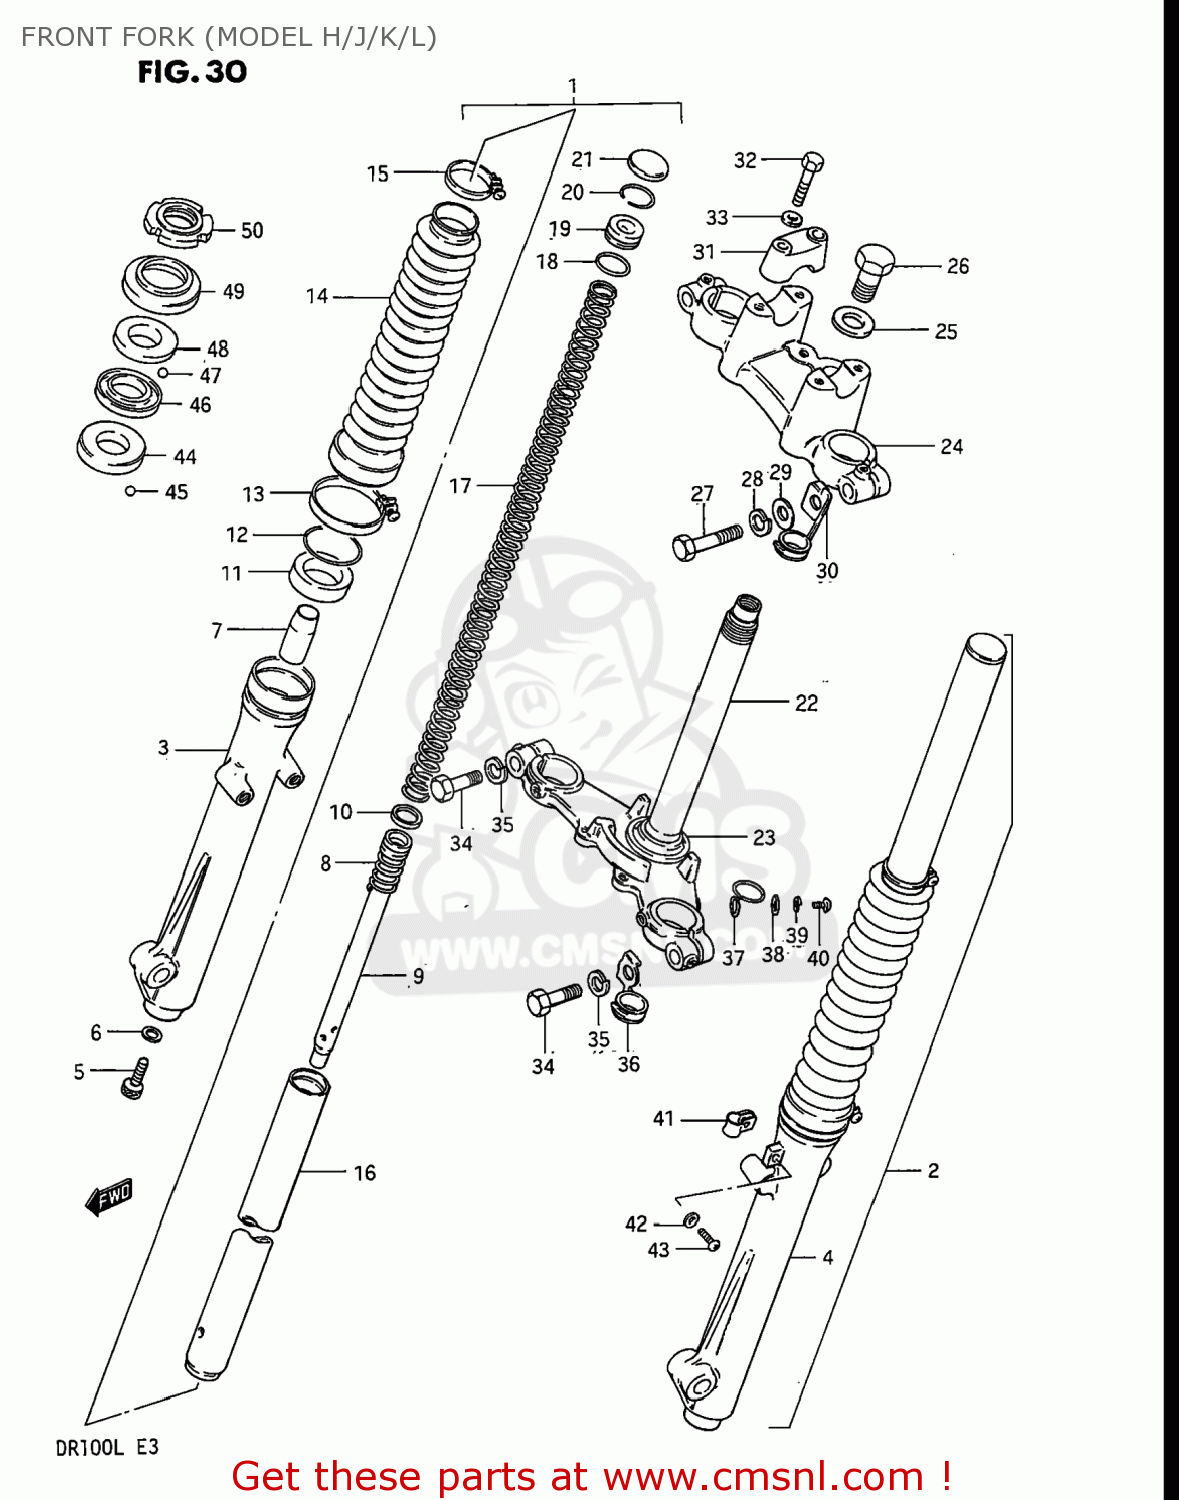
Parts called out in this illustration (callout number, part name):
1	DAMPER ASSEMBLY,RIGHT
2	DAMPER ASSEMBLY,LEFT
3	TUBE,OUTER,RIGHT
4	TUBE,OUTER,LEFT
5	BOLT(8X27)
6	GASKET (NAS)
7	PIECE,OIL LOCK
8	SPRING,REBOUND
9	CYLINDER,FRONT FORK
10	RING
11	SEAL,OIL
12	CIRCLIP,FORK OIL SEAL
13	BAND,FRONT FORK BOOT
14	BOOT
15	BAND,FRONT FORK BOOT
16	TUBE,FORK,INNER
17	SPRING,FRONT FORK
18	O RING
19	SEAT,SPRING
20	RING,STOPPER
21	CAP,FR FORK
22	STEM,STEERING
23	RACE,STEERING OUTER LWR
24	HEAD,STEERING STEM
25	WASHER
26	BOLT,STEERING STEM HEAD
27	BOLT
28	WASHER,LOCK
29	WASHER 10MM
30	GUIDE,CABLE
31	HOLDER,HANDLE UPR
32	BOLT
33	WASHER,LOCK,8.
34	BOLT
35	WASHER,LOCK
36	GUIDE,CABLE
37	CLIP
38	WASHER
39	WASHER,LOCK
40	SCREW 6X12
41	CLIP,FR BRAKE CABLE
42	LOCK WASHER
43	SCREW
44	LACE,STEERING INNER LWR
45	BALL
46	RACE,STEERING INNER UPR
47	BALL
48	RACE,STEERING OUTER UPR
49	DUST SEAL,STEERING UPR
50	NUT,STEERING STEM(25X44X10)
